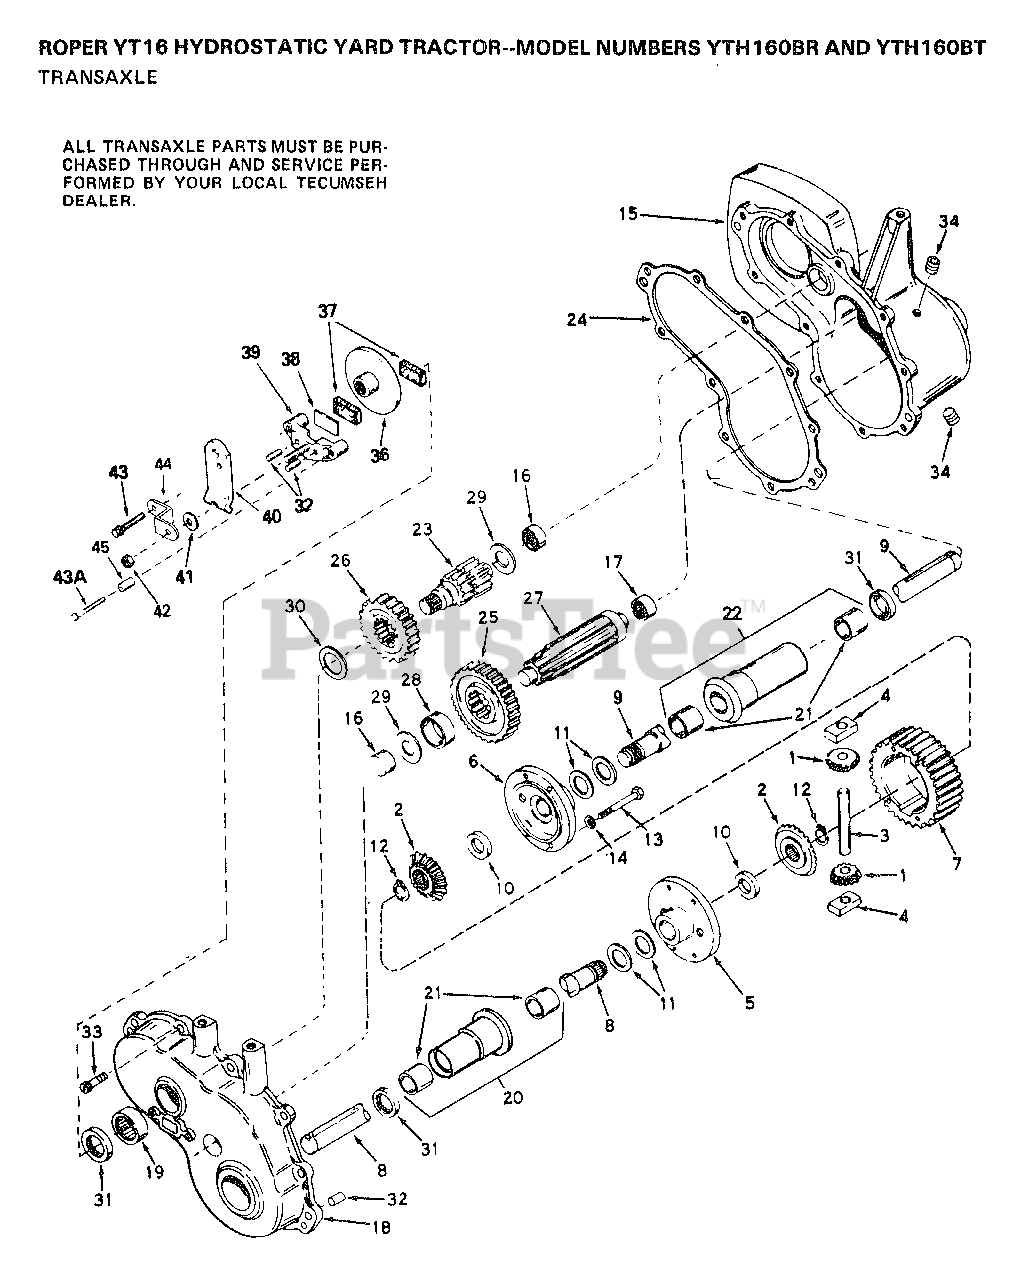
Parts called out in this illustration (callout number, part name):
1	PINION, 10T
4	BLOCK DRIVE
5	CARRIER, DIFFERENTIAL
6	CARRIER, DIFFERENTIAL
11	WASHER THRUST
13	SCREW, 1/4-20 X 2-1/4
14	WASHER LOCK 1/4
16	BEARING, NEEDLE
17	BEARING, NEEDLE
19	BEARING, NEEDLE
20	HOUSING & BUSHING ASSY
22	HOUSING & BUSHING ASSY
23	SHAFT, BRAKE
25	GEAR, OUTPUT
26	GEAR, IDLER
27	SHAFT, OUTPUT
30	WASHER, THRUST
36	DISK, BRAKE
38	PLATE BRAKE PAD
39	HOLDER BRAKE PAD
40	LEVER, BRAKE
41	WASHER, FLAT
42	LOCKNUT 5/16-24
43	SCREW, 1/4-20 X 1-1/4
43A	SCREW FLNG HEX 1/4-20 X 2-1/4
44	BRKT BRAKE LEVER
